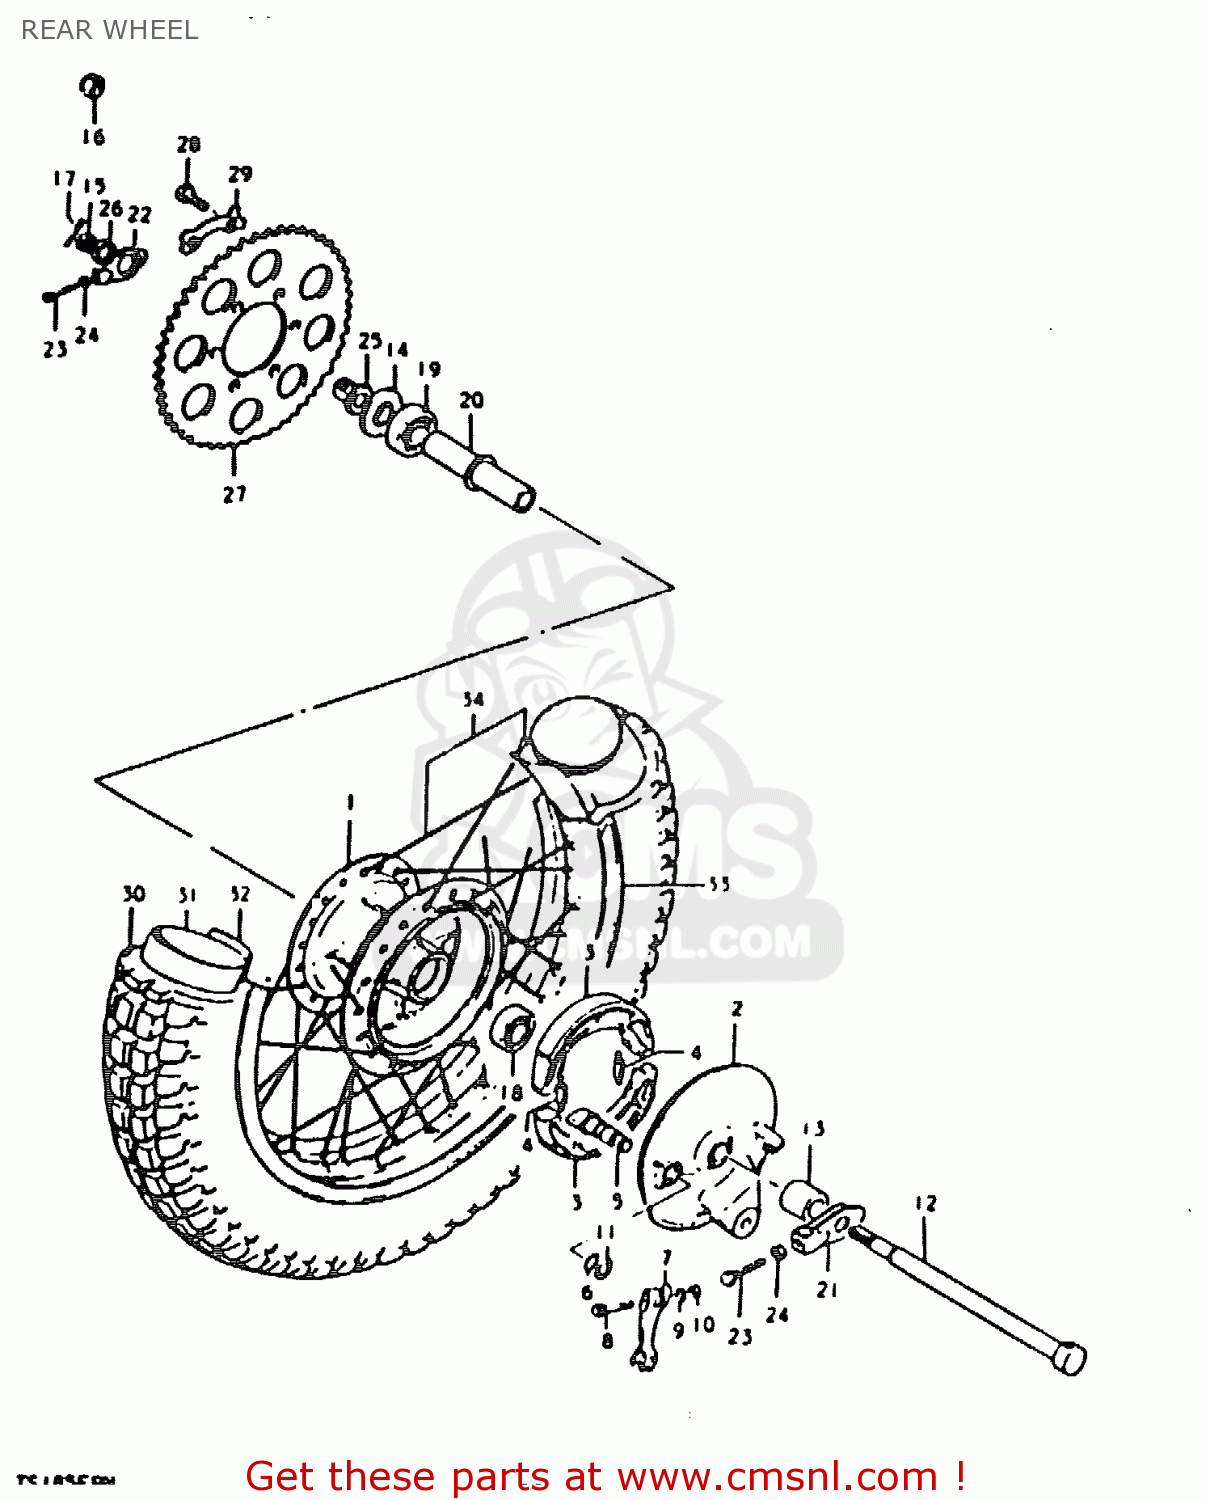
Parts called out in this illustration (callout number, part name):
1	HUB,REAR WHEEL
2	PANEL,RR BRAKE ANCHOR
3	SHOE,BRAKE
4	SPRING(L:34)
5	CAM,FRONT BRAKE
6	O-RING (D:2.4 ID:13.8)
7	LEVER,REAR BRAKE CAM
8	BOLT(6X33)
9	WASHER
10	NUT
11	WASHER (14.5X22X1.6)
12	AXLE,REAR
13	SPACER(15.2X22X26)
14	SPACER,RR AXLE,L
15	NUT 12MM
17	COTTER PIN
18	BEARING
19	BEARING
20	SPACER,RR WHEEL HUB BEARING
21	ADJUSTER,CHAIN
22	ADJUSTER,CHAIN,L
23	BOLT(8X40)
24	NUT
25	SPACER,CHAIN ADJUSTER,L
26	NUT
27	SPROCKET,RR
28	BOLT(8X30)
29	WASHER
30	TIRE 4.10-18 105-458MM
31	TUBE ASSEMBLY,WHEEL,INNER
32	PROTECTOR,INNER TUBE
33	RIM,WHEEL(1.85X18)
34	SPOKE SET,REAR
